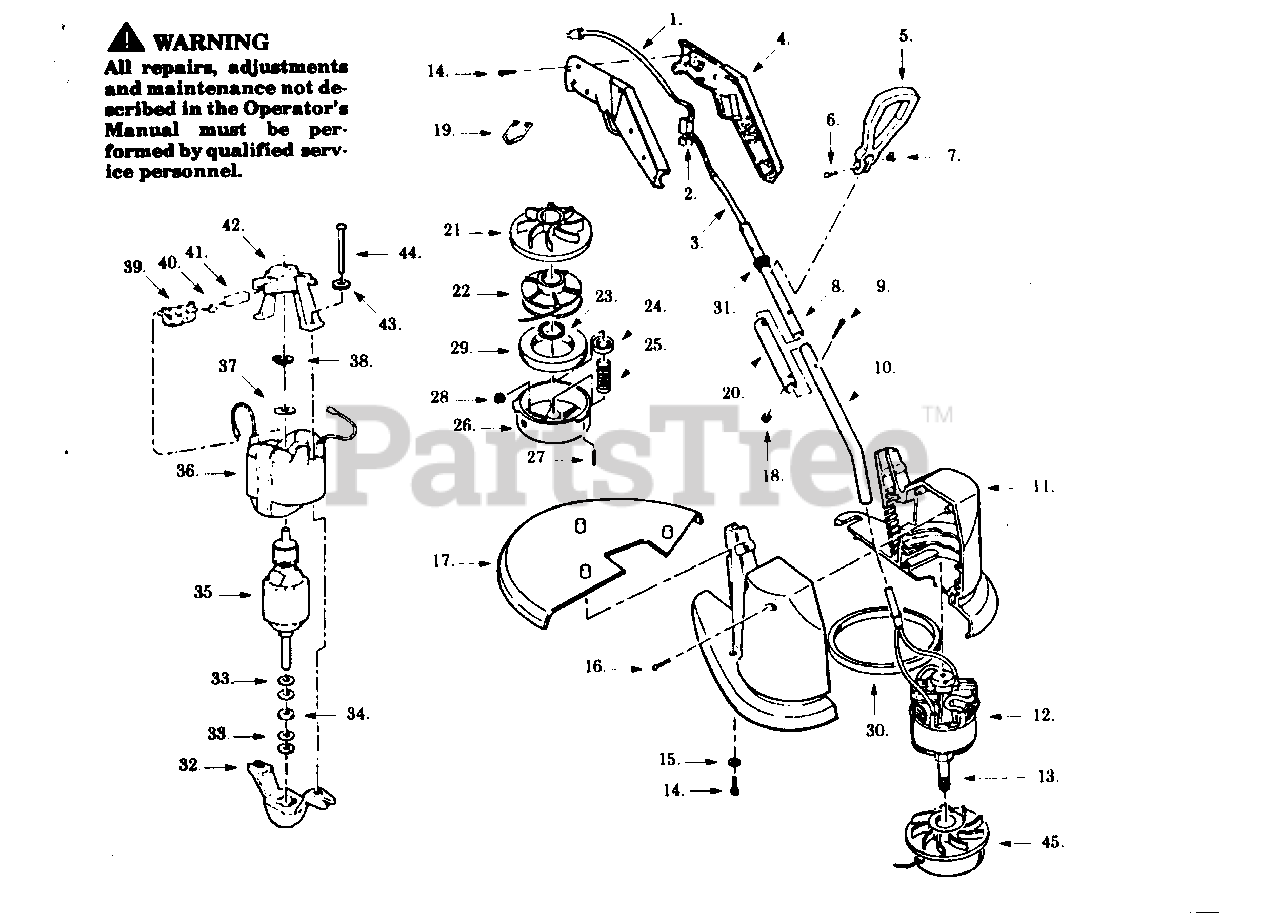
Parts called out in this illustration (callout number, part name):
1	Power Cord
4	R.H./L.H. Handle
5	Assist Handle
7	Wing Nut
8	Upper Tube
10	Lower Tube
11	Motor Housing
13	Shaft Adapter
17	Guard Ass'y.
20	Outer Tube
21	Rear Plate
22	Spool & Line
24	Adapter Nut
26	Hub Ass'y.
27	Cotter Pin
29	Foam Pad
32	Endbell Ass'y. (Drive)
34	Wave Washer
35	Armature Ass'y.
36	Field Ass'y.
38	Retaining Ring
39	Brush Holder
40	Brush Spring
42	Endbell Ass'y. (Brush)
43	Lockwasher
45	Cutting Head Ass'y.
